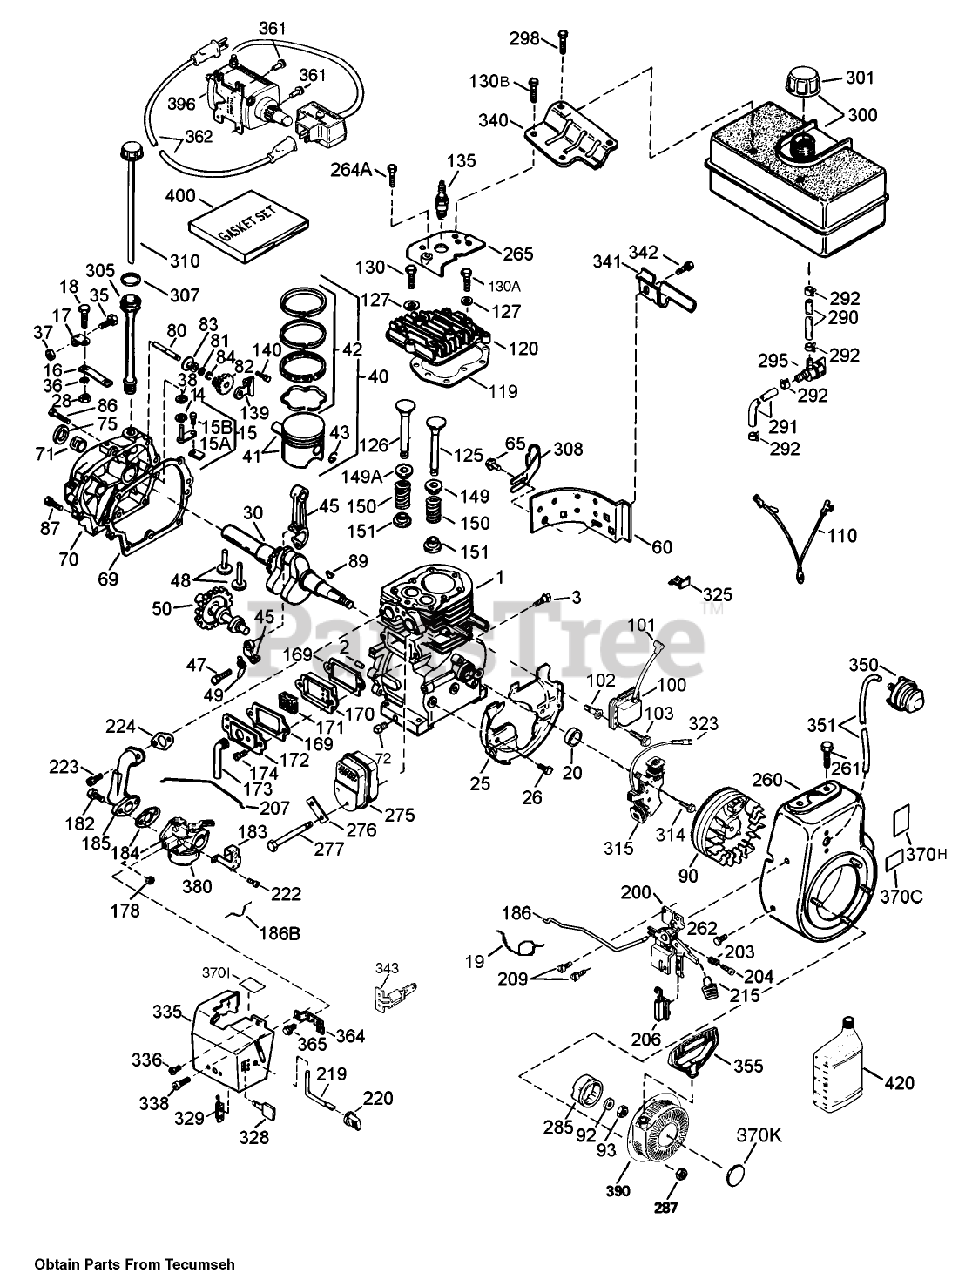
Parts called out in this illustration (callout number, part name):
1	Cylinder Asm (Includes 2, 20, 72)
2	Pin-Dowel
3	Screw (1/4-20x1/2)
14	Washer-Flat
15	Rod, Governor (Incl. Nos.62 63)
15A	Yoke-Governor
15B	Screw (6-40x5/16)
16	Lever-Governor
17	Clamp-Lever, Governor
18	Screw (T-15, 8-32x7/16)
19	Spring-Throttle
20	Seal-Oil
25	Baffle-Housing, Blower
26	Screw (1/4-20x19/32)
28	Nut-Lock
30	Crankshaft
35	Screw
36	Washer-Lock
37	Nut-Lock
38	Ring-Retaining
40	TANK PAD
40	Piston- Pin and Ring Set (.010 O S)
41	Piston and Pin ASM (STD) (Includes 43)
41	J-BOLT
42	BUSHING TRANS 7/8 BORE
42	BUSHING - ENG 1" BORE
45	Connecting Rod Asm (Includes 47, 49)
47	Bolt-Rod, Connecting
48	Lifter-Valve
49	Dipper-Oil
50	Camshaft (MCR)
60	Extension-Housing, Blower
65	Screw
69	Gasket-Cover, Cylinder
70	Cover-Cylinder (Includes 71, 75, 80)
71	2025A77 WIZARD ROTA
72	Plug-Drain, Oil (SQH 1/4-18)
75	Seal-Oil
80	Shaft-Governor
81	Washer-Flat
82	Gear Assy., Governor (Incl. Ref. #45)
83	Spool-Governor
84	Ring-Retaining
86	Screw (1/4-20x1-3/16)
87	Screw (1/4-20x1-11/16)
89	Key-Flywheel
90	Flywheel ASM
92	Washer-Belleville
93	Nut-Flywheel
100	Solid State ASM
101	Cover-Spark Plug
102	Stud-Mounting, Solid State
103	Screw (T-15, 10-24 x 15/16)
110	Wire-Ground
110A	Wire-Ground
119	Gasket-Head, Cylinder
120	Head-Cylinder
125	Valve, Exhaust (Standard)(Incl. No. 9)
125	Valve, Exhaust (1/32" oversize)(Incl. No. 9)
126	Valve, Intake (Std.) (Incl. Ref. #58)
126	Valve, Intake (1/32" oversize) (Incl. Ref. #58)
127	Washer-Flat
130	Screw (5/16-18x1-1/2)
130A	Screw (5/16-18x1-25/32)
130B	Screw (5/16-18x39/64)
135	Spark Plug-Resistor (R J19 L M)
139	Bracket-Gear, Governor
140	Screw (10-24x1/2)
149	Cap-Spring, Valve
149A	51106 GILSON ROTARY
150	Spring-Valve
151	Keeper-Spring, Valve
169	Gasket-Cover, Valve
170	Body-Breather
171	Element-Breather
172	Cover-Valve
173	Tube-Breather
174	Screw
178	Nut and Lock Washer (1/4-28)
182	Screw (1/4-28x1)
183	Bracket-Choke
184	Gasket-Carburetor To Intake Pipe
185	Pipe-Intake
186	Link-Governor
186B	Spring-Choke
200	Bracket-Control (Includes 19, 203, 204, 206)
203	Spring-Compression
204	Screw (T-10, 5-40x7/16)
206	Terminal
207	Link-Throttle
209	Screw (10-32 x 1/2)
215	Knob-Control
219	Rod-Choke
220	Knob-Control
222	Screw (10-32 x 1/2)
223	Screw (T-30, 5/16-18x1-3/32)
224	Gasket-Pipe, Intake
260	Housing-Blower
261	Screw (5/16-18x3/4)
262	Screw
264A	Screw (1/2-20x5/8)
265	Cover-Cylinder Head
275	Muffler
276	62513 SNWTHWR W/284
277	Screw (5/16-18x4-3/16)
285	Cup-Starter
287	Nut and Lock Washer (1/4-28)
290	Line-Fuel (8.62)
291	Line-Fuel
292	Clamp-Line, Fuel
295	Valve-Shut Off, Fuel
298	Screw (1/4-15x7/8)
300	Tank-Fuel (Includes 292, 301)
301	Cap-Fuel
305	Tube-Fill, Oil
307	O-Ring
308	Knob-Control
310	Gauge Oil ASM
314	Screw (1/4-20 x 3/4)
315	Coil-Alternator, 18 Watt (Includes 323)
323	Terminal
325	Clip-Wire
328	Key-Ignition
329	Terminal
335	Cover-Carburetor
336	Screw (10-32x1/2)
338	Screw (10-32 x 3/8)
340	Bracket-Tank, Fuel (Black)
341	Bracket-Tank, Fuel
342	Screw (1/4-20x19/32)
343	Bracket-Switch, Key
350	Primer ASM
351	Line-Primer
355	Handle-Starter, Mitten Grip
361	Screw (T-30, 1/4-20x15/32)
362	Cord-Extension (10-6)
364	Bracket-Carburetor
365	Screw (8-32x27/64)
370C	Decal-Primer, International Symbol
370H	Decal-Speed Control and Choke
370I	Decal-Warning (Bilingual)
370K	Decal-Tecumseh Logo for Top of Recoil Starter
380	Carburetor ASM
390	Starter-Rewind
396	Starter-Electric (110 Volt)
400	Gasket Set
420	Oil-Engine, S A E 5W30
